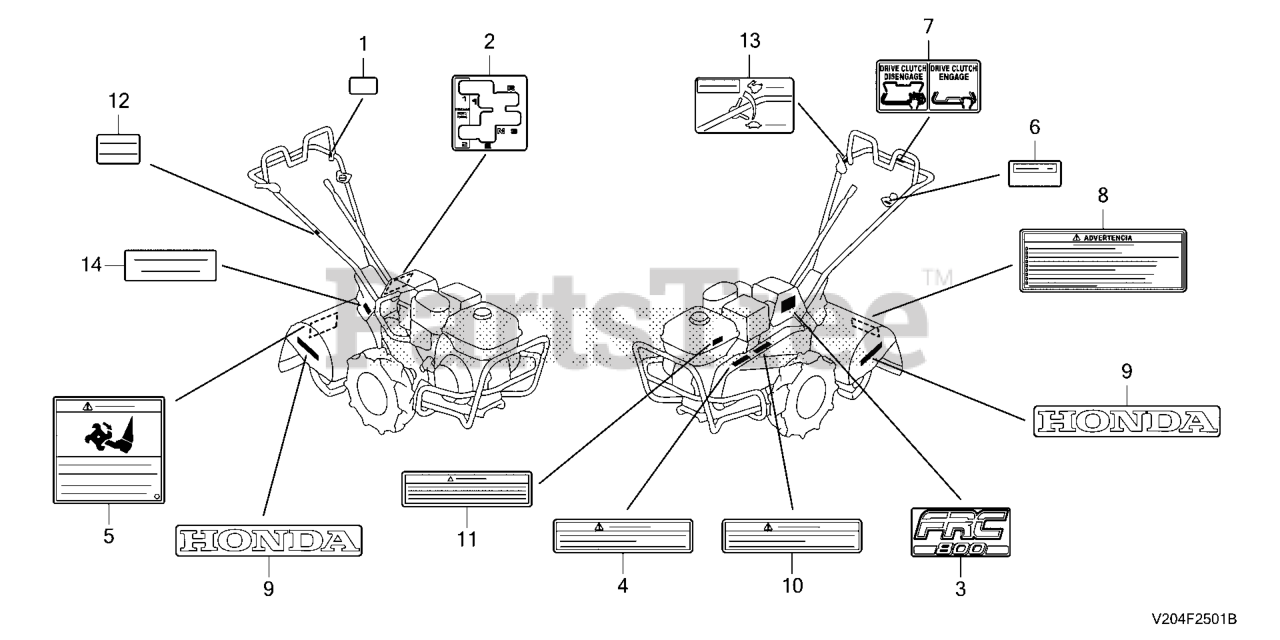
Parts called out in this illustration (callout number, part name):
1	SEAL, PROTECTOR (NOT AVAILABLE)
2	MARK, CHANGE (ENGLISH)
3	MARK, STRIPE
4	LABEL, BELT COVER CAUTION (ENGLISH)
5	LABEL, TINE DANGER (ENGLISH)
6	MARK, ENGINE SWITCH INDICATION
7	MARK, MAIN CLUTCH INDICATION
8	LABEL, OPERATOR WARNING (ENGLISH)
9	MARK, HONDA EMBLEM
10	LABEL, EX. CAUTION (ENGLISH)
11	LABEL, SPARK WARNING
12	MARK, HOLD POSITION
13	MARK, THROTTLE INDICATION (ENGLISH)
14	LABEL, WARNING
